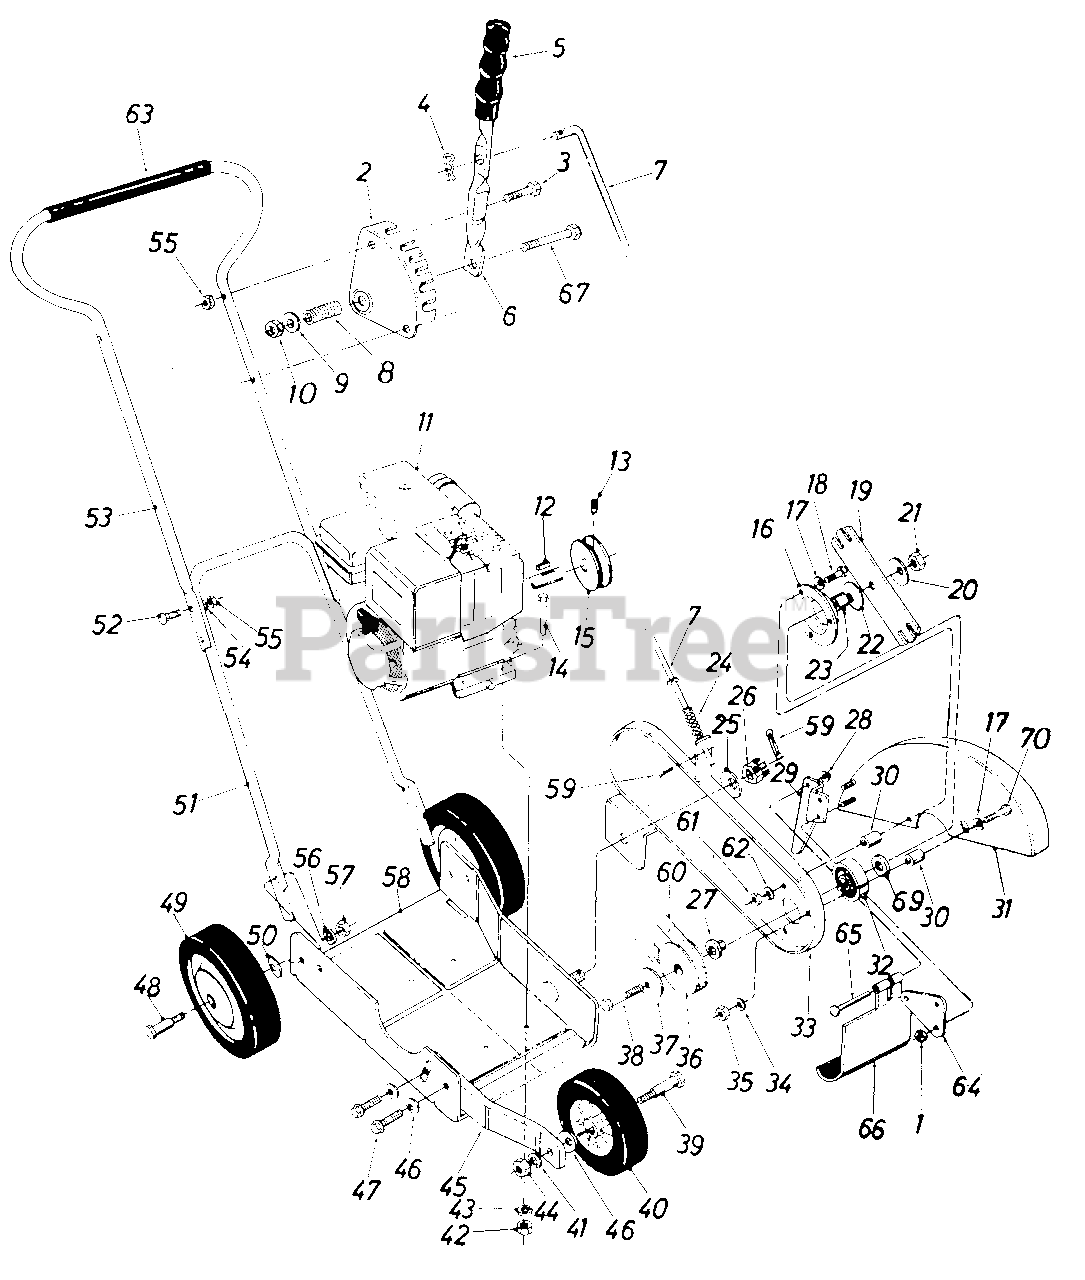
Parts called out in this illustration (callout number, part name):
1	Hex Cent. L.Nut 1/4-20 Thd.
3	Hex Bolt 1/4-20 x 1.25" Lg.*
4	Cotter Pin 1/8" Dia. x 1.0" Lg. *
5	Grip
7	Clutch Rod
8	Compression Spring .50" O.D. x 1.38" Lg.
9	Fl.Wash. .34" I.D. x .62" O.D. x .063
10	Hex Cent L. Nut 5/16-18 Thd.
11	Engine
12	Sq.Key 3/16 x 1.0" Lg.*
13	Set Scr. 1/4-28 x 1/4" Lg.
14	Hex Bolt 5/16-18 x 1.50" Lg.*
15	Engine Pulley
16	Bearing Housing
17	Bell.Wash. .34" I.D. x 88" O.D. x .060
18	Hex Bolt 5/16-18 x 1.25" Lg.*
20	Bell.Wash. .535" I.D. x 1.50" O.D. x.052
21	Hex Cent. L.Nut 1/2-20 Thd.
22	Bell.Wash. .535" I.D. x 1.50" O.D. x. 52
23	Spacer
24	Compression Spring .57" O.D. x 1.92" Lg.
25	Bell.Wash. .535" I.D. x 1.50" O.D. x .052
26	Hex Castle Nut 1/2-20 Thd.
27	Shoulder Spacer
28	Push Cap
29	Guide
30	Spacer.354" I.D. x.635" O.D. x .510" Lg.
33	Spindle B racket Ass'y.
34	L.Wash. 5/16" I.D.*
35	Hex Nut 5/16-18 Thd.
36	1 Pulley Half
37	Bell.Wash. .535" I.D. x 1.50" O.D. x .052
38	Hex Bolt 1/2-20 x 3.50" Lg.*
39	Shoulder Bolt .498" Dia. x 1.450
40	WheelAss'y.Comp.6" Dia. x 1.50
41	L.Wash. 3/8" I.D.*
42	Hex Nut 5/16-18 Thd.*
43	L.Wash. 5/16" I.D.*
44	Hex Nut 3/8-16 Thd.*
45	Front Wheel Support
46	Bell.Wash. .400" I.D. x 88" O.D. x.060
47	Hex Wash. Hd. Self Tap Scr. 3/8- 16 x .75" Lg.
48	Shoulder Bolt .498" Dia. x 1.450
49	Wheel Ass'y. Comp. 7" Dia. x 1.50
50	Bell.Wash. .400" I.D. x 88" O.D.
51	Lower Handle
52	Carriage Bolt 1 /4-20 x 1.25 "
53	Upper Handle
54	L.Wash. 1/4" I.D. *
55	Hex Nut 1/4-20 Thd.*
56	L.Wash. 3/8" I.D.*
57	Hex Nut 3/8-16 Thd.*
58	Base Ass'y.
59	Cotter Pin 1/8" Dia. x 1.0"
60	3V-Belt 31.2" Lg.
61	Hex Nut 5/16-18 Thd.#
63	Grip
64	Flap Bracket
65	Hinge Pin
66	Debris Defiector
67	Hex Bolt 5/16-18 x 1.75" Lg. *
69	Fl.Wash. .51 I.D. x 1.00 O.D. x .060
70	Hex Bolt 5/16-18 x 2.00" Lg.*
